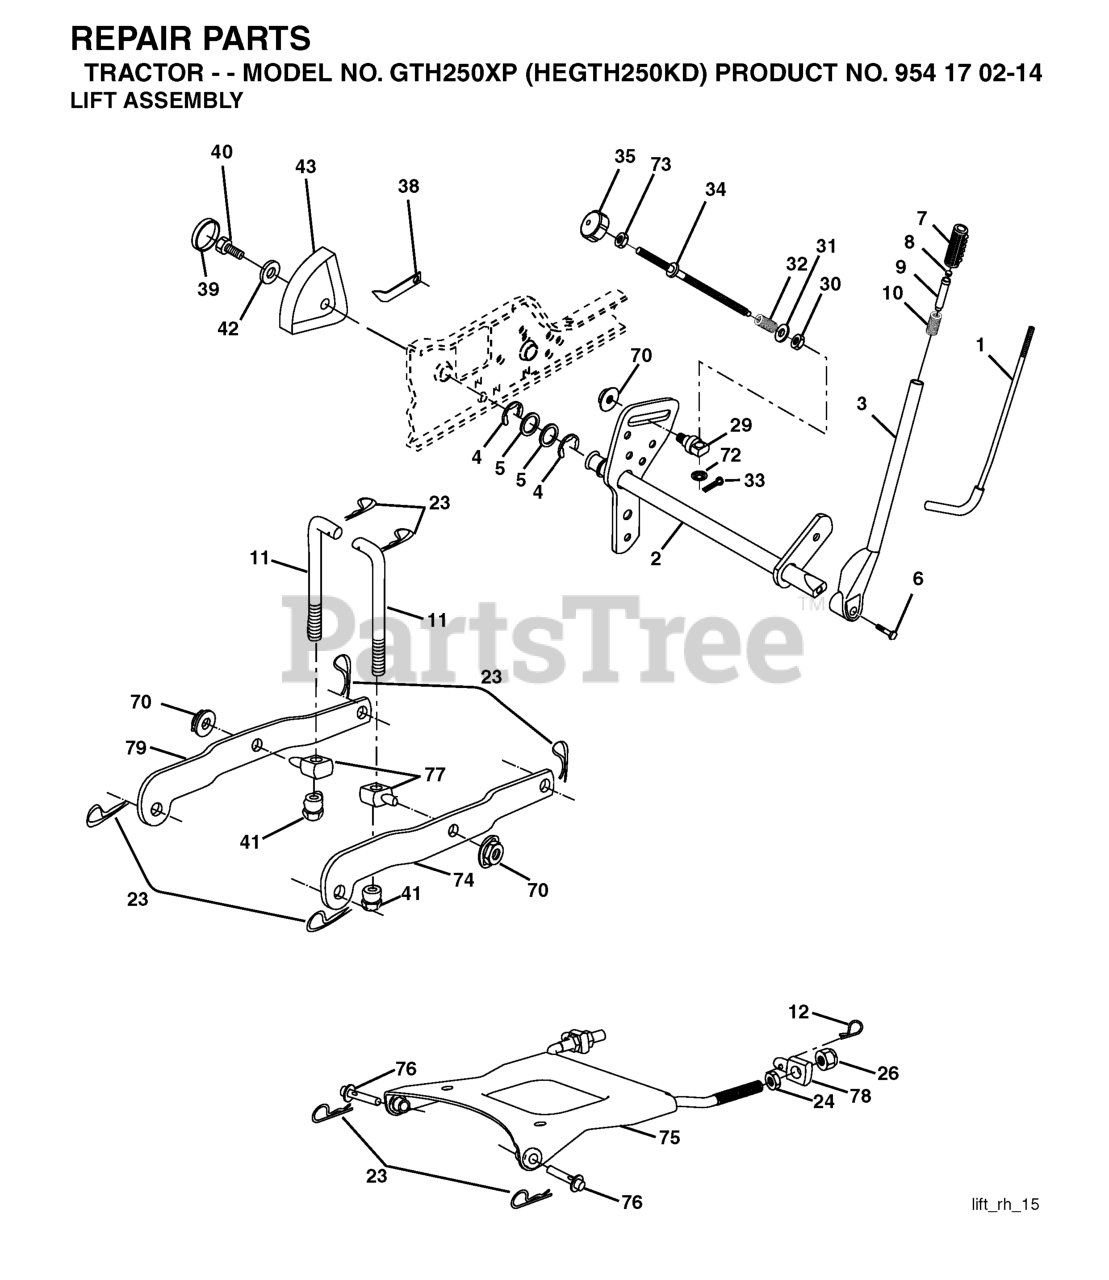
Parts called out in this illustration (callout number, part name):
1	LEVER ROD LT
2	SHAFT ASM., LIFT VGT
3	LEVER ASSY-LIFT RH
5	Washer 29/32 x 1 - 1/4 x 16 Ga.
6	Bolt, Fin Hex 3/8-16 x 1-1/12
7	GRIP HANDLE
8	PLUNGER BUT KIT
9	PLUNGER BUT KIT
10	SPRING 0.620D X 2.125
11	LIFT LINK
12	SPRING RETAINER
23	RETAINER-SPRNG RB
24	NUT.HEX.JAM.1/2-13
26	NUT LTV
32	SPRING.COMP.INF.H
33	COTTER PIN
34	ROD.LIFT.ADJUSTABLE
35	KNOB INF 3/8-16
38	POINTER, HEIGHT INDICATOR(2 2)
40	SCREW 5/16-18X1
41	NUT, LIFT LINK 7/16-20
43	HEIGHT INDICATOR
70	NUT
72	NUT PUSH M
73	NUT
74	ARM SUSP REAR RH
75	PLATE ASM SUSP FRONT
76	PIN.FLANGE
79	ARM SUSP. REAR LH
